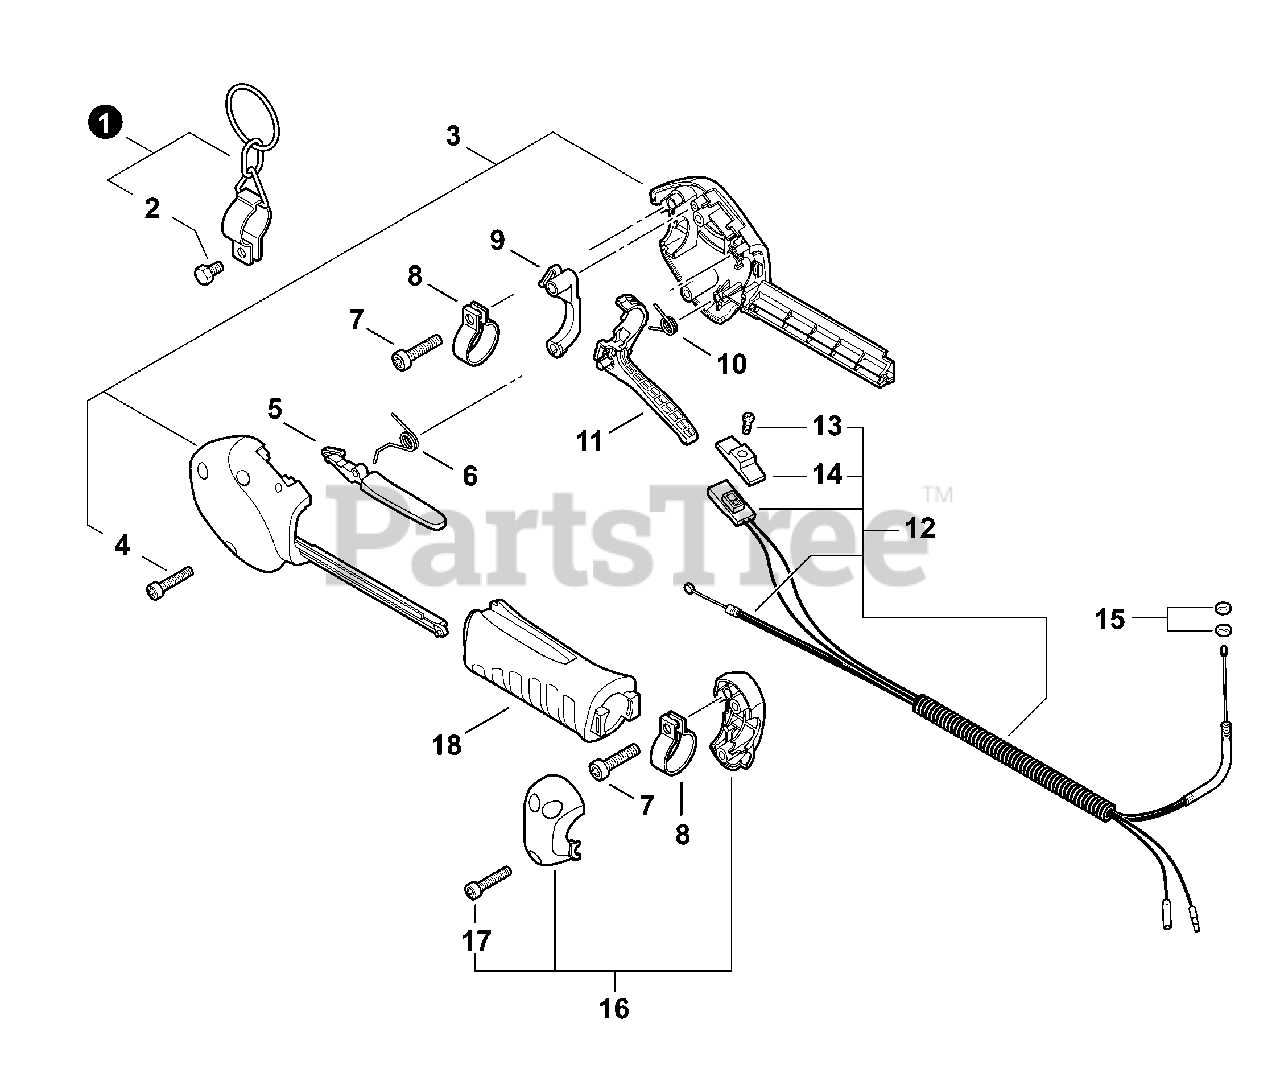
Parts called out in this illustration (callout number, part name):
1	HANGER SET, HARNESS
2	BOLT 5×12
3	HANDLE KIT, CONTROL
5	LEVER, THROTTLE LOCKOUT
6	SPRING, TORSION
7	BOLT 5×20
9	LOCKOUT, THROTTLE
10	SPRING, TORSION
11	TRIGGER, THROTTLE
12	CABLE ASSY, CONTROL
13	SCREW 3×10
14	KNOB, SWITCH - ORANGE
16	FIXTURE SET, HANDLE
18	GRIP, HANDLE
